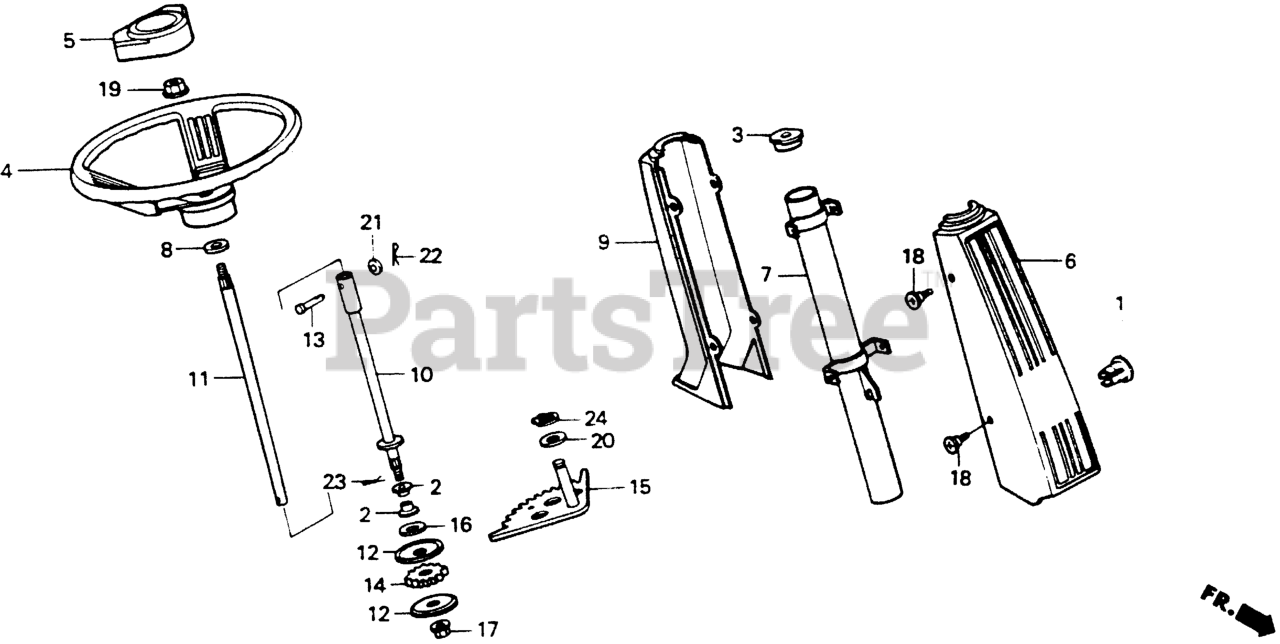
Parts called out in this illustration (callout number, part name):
1	PLUG, CROSS PIPE SETTING
2	BUSH (17X22X15)
3	BUSH, STEERING SHAFT
4	WHEEL, STEERING
5	PAD, CENTER
6	COVER, FR. COLUMN
7	COLUMN, STEERING (NOT AVAILABLE)
8	WASHER, STEERING COLUMN
9	COVER, RR. COLUMN
10	SHAFT, STEERING
11	SHAFT, STEERING WHEEL
12	WASHER (14.2X44)
13	PIN (7X30)
14	GEAR, STEERING DRIVE
15	GEAR, STEERING DRIVEN (NOT AVAILABLE)
16	WASHER, PIVOT BOLT (NOT AVAILABLE)
17	NUT, AXLE (10MM)
18	SCREW, SPECIAL (6X12)
19	NUT, SELF-LOCK (OHASHI)
20	WASHER, THRUST (17MM)
21	WASHER, PLAIN (7MM) (NOT AVAILABLE)
22	PIN, COTTER (2.0X15)
23	PIN, SPLIT (3.0X22)
24	CIRCLIP (OUTER) (17MM)
